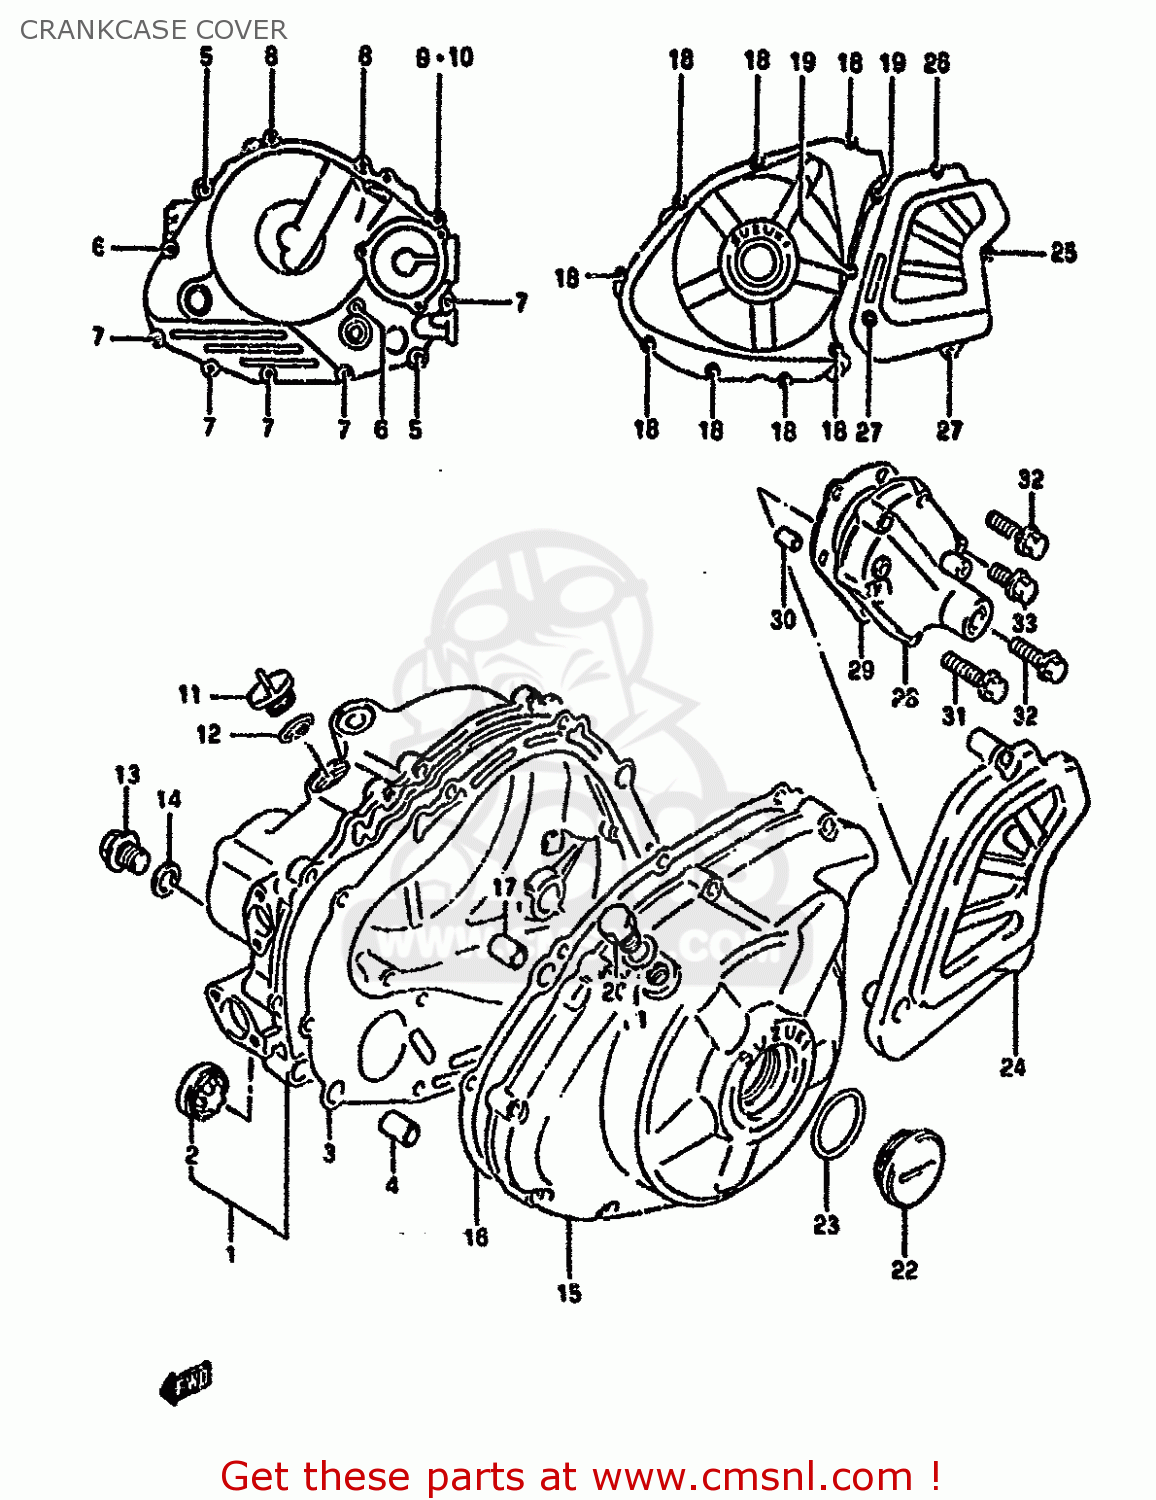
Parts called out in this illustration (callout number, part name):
1	COVER,CLUTCH
2	LENS,OIL LEVEL CHECK
3	GASKET,CLUTCH COVER (NAS)
4	PIN
5	BOLT
6	BOLT
7	BOLT
8	BOLT
9	BOLT
10	WASHER
11	PLUG
12	O RING(D:3.1,ID:16.8)
13	PLUG(14X12)
14	GASKET(13.8X18.8X4.8) (NAS)
15	COVER,GENERATOR
16	GASKET,MAGNETO COVER (NAS)
17	PIN
18	BOLT
19	BOLT
20	PLUG,12X9
21	GASKET(12.1X16.2X3.7) (NAS)
22	PLUG (36X10)
23	O RING(D:3.1,ID:32.7)
24	COVER,ENGINE SPROCKET
25	BOLT
26	BOLT
27	BOLT
28	COVER,GEAR SHIFT
29	GASKET,GEAR SHIFT COVER (NAS)
30	PIN
31	BOLT
32	BOLT
33	BOLT
